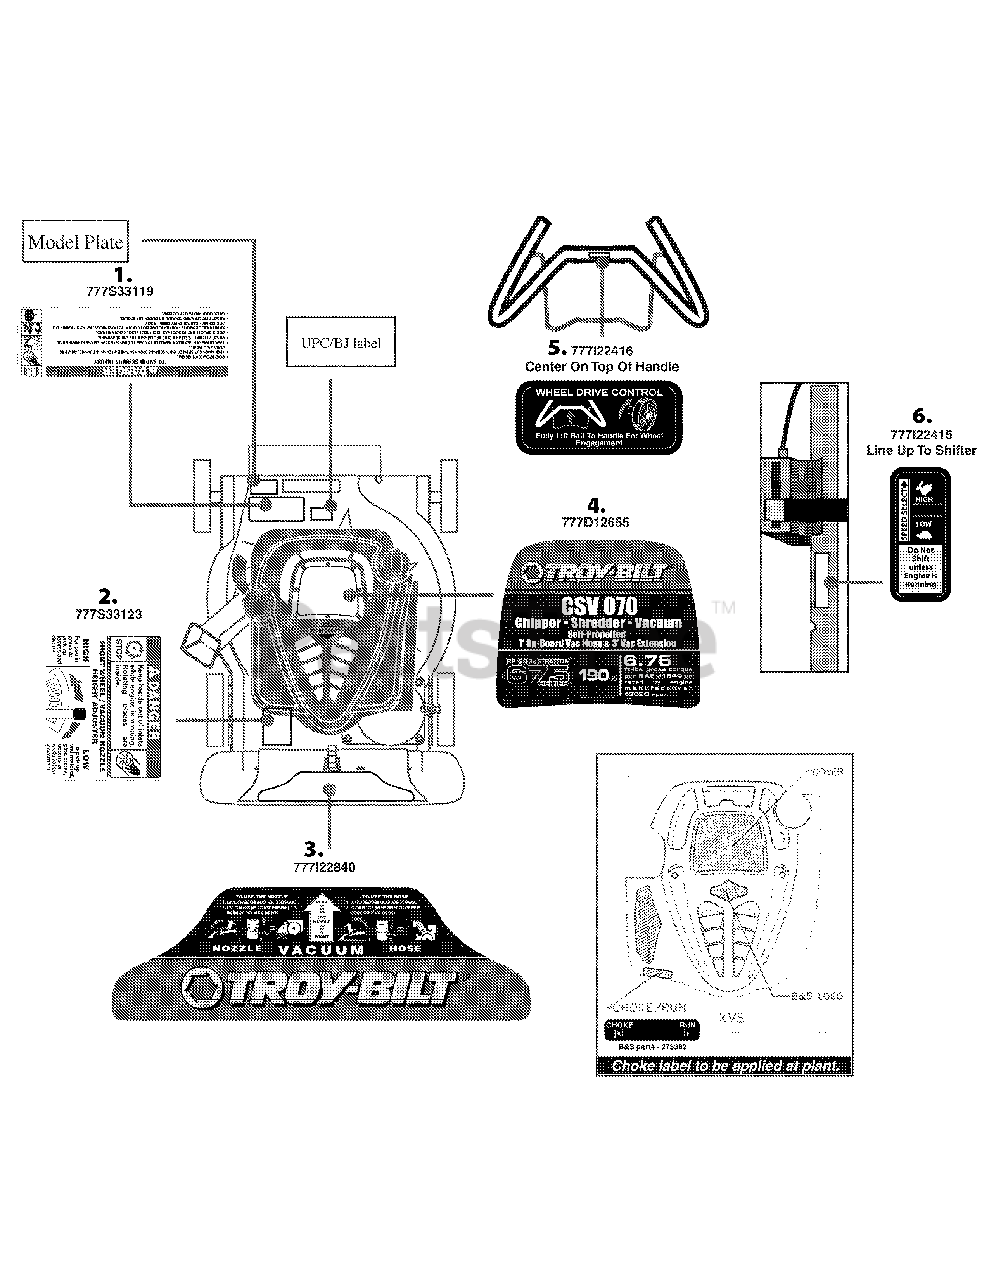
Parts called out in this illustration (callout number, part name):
1	LABEL-CSV DANGER
2	LABEL-CSV BLADES DANGER
3	LABEL-CSV NOZZLE TROY
4	LABEL-CSV:SHD/XVS:TBILT
5	LABEL-HANDLE
6	LABEL-HANDLE
